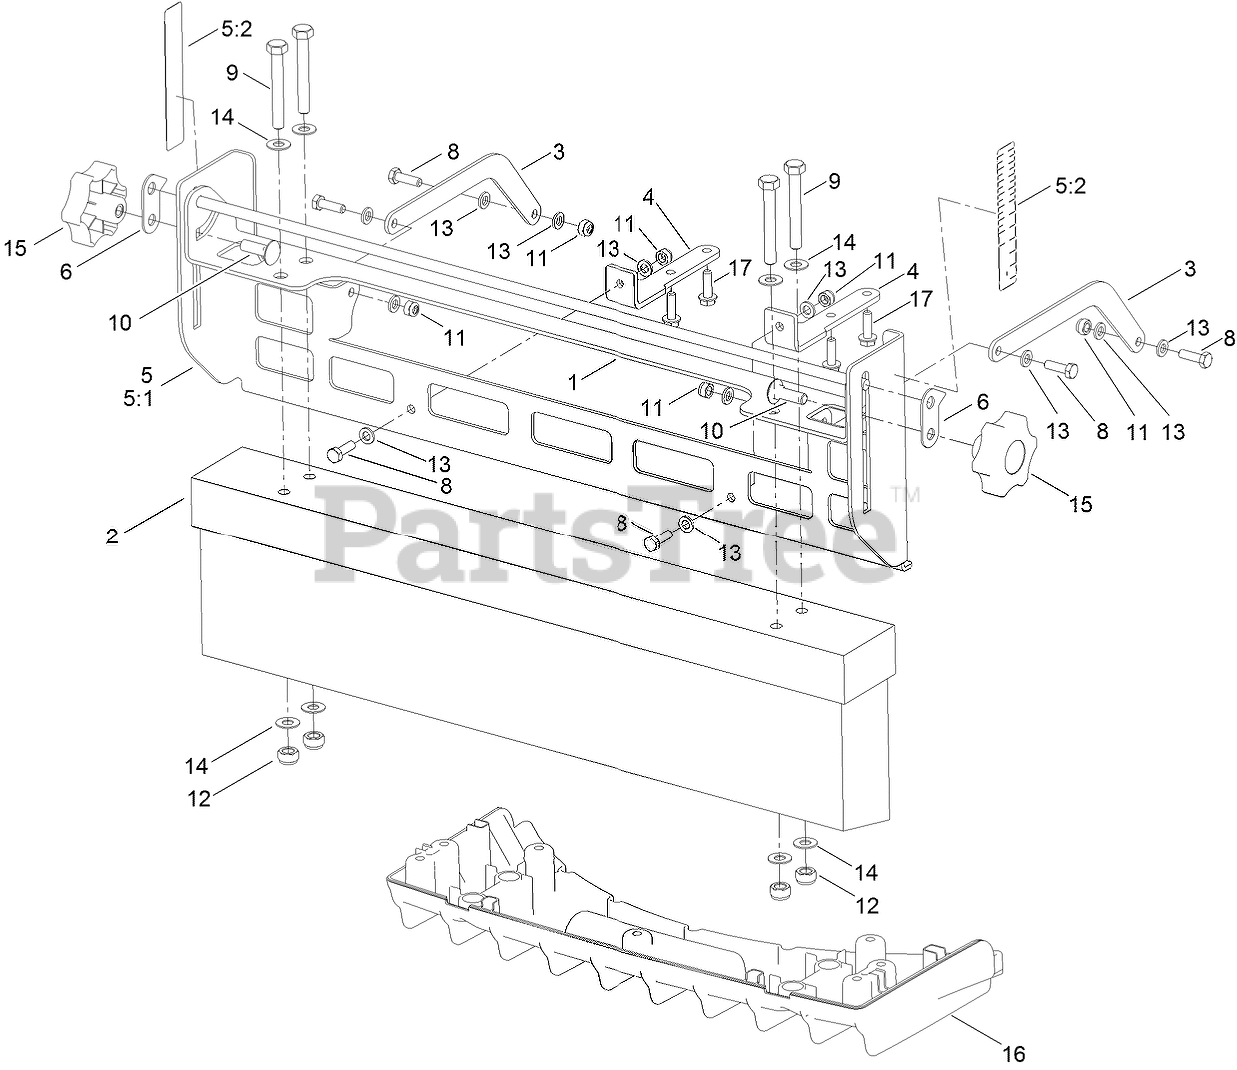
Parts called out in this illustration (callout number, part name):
1	BRACKET-BRUSH
3	STRUT-BRUSH
4	BRACKET-LOWER, BRUSH
5	BRACKET-BRUSH W/ DECALS
5:1	BRACKET-ADJUSTMENT, BRUSH
5:2	DECAL-HEIGHT, BRUSH
6	PLATE-HEIGHT, BRUSH
8	SCREW-HH
9	BOLT
10	BOLT-COACH
11	NUT-NYLOC
12	NUT-HEX, NI
13	WASHER-PLAIN
14	WASHER
15	KNOB-HANDLEBAR
16	FIN-FRONT
17	SCREW-TAPTITE
